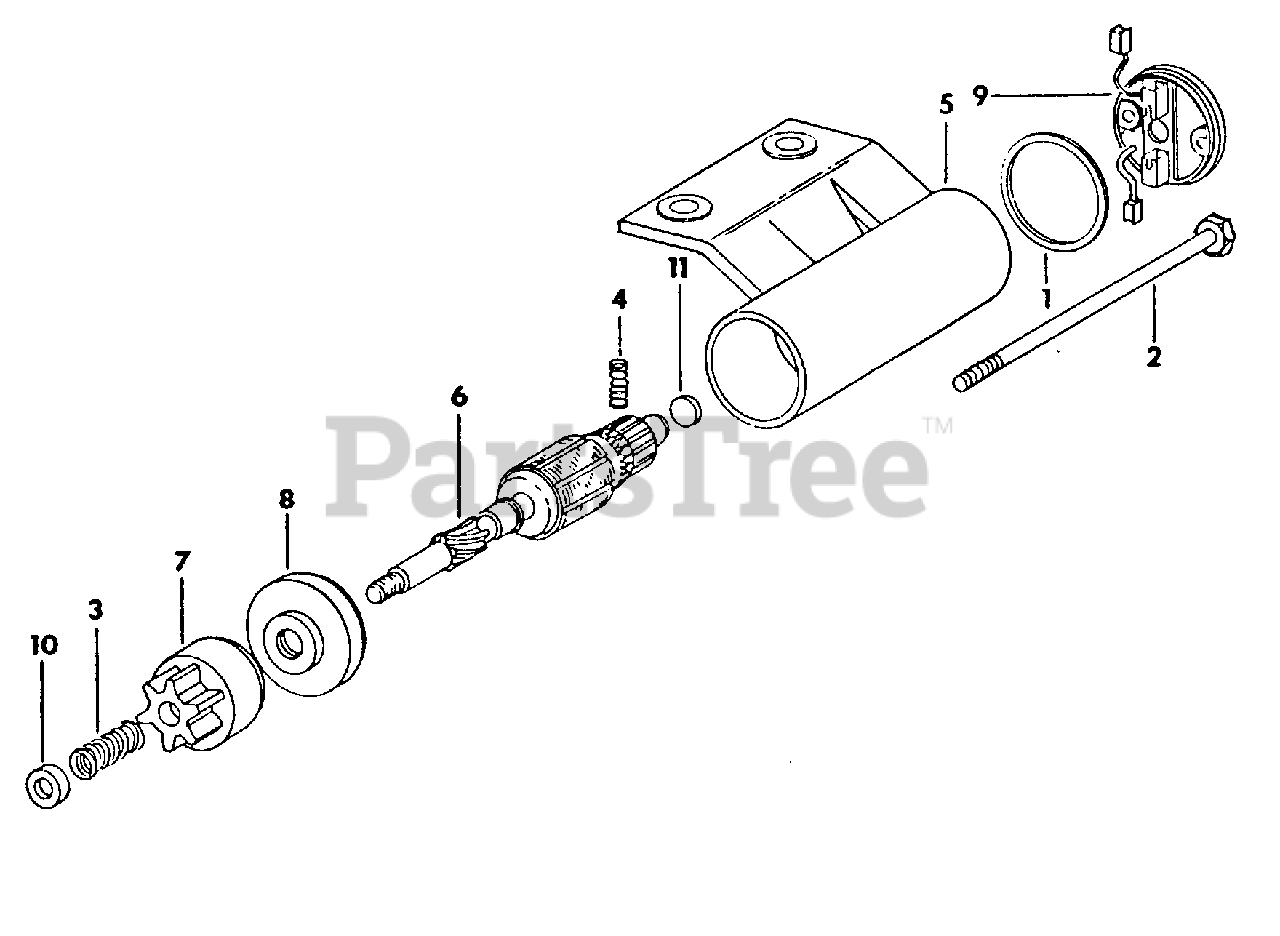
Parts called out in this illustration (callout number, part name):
1	Gasket, Cap
2	Screw, Attaching
3	Spring, Anti-Drift
4	Spring, Brush
5	Housing Assy, Motor
6	Armature Assy
7	Pinion Assy, Torsion Drive
8	Cap Assy, Drive End
9	Cap Assy, Commutator End
10	Stop, Pinion
11	Disc, Thrust
